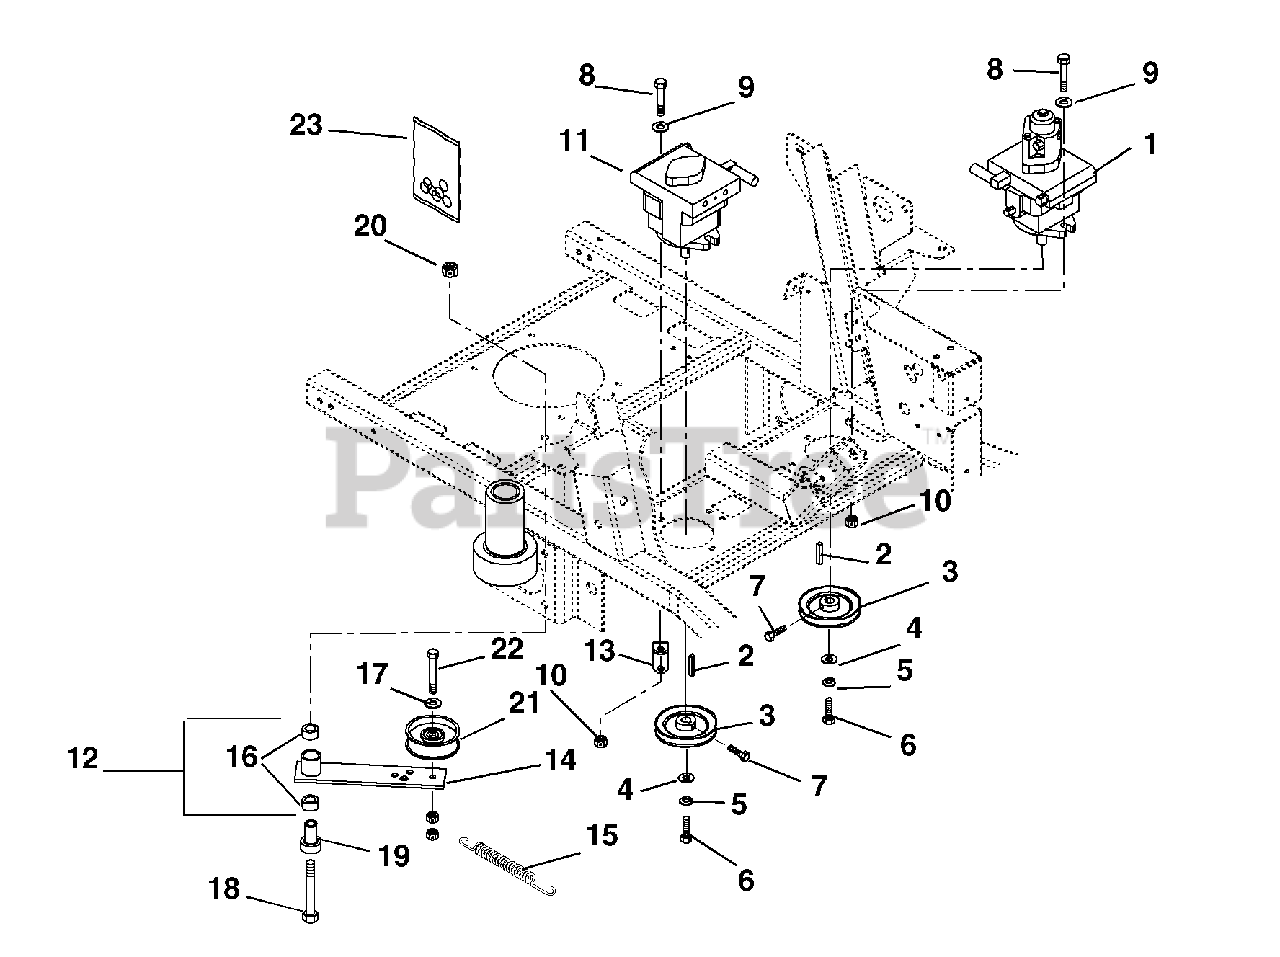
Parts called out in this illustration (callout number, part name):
1	Hydrostat BDP with Auxiliary
2	Key-Straight 5mm x 25mm x 5mm
3	Sheave 4.0 x .199
4	Washer-Flat-Steel .25 x 1.0 x .048
5	Washer-Locking .25 x .062
6	Bolt-Hex M6 x 1.0 x 12
7	Bolt-Hex .25-20 x .50 Grade 5
8	Bolt-Hex .38-16 x 1.25 Grade 5
9	Washer-Flat-Steel .390 x .75 x .125
10	Nut-Locking-Center .38-16
11	Variable-Displace Pump
12	Assembly,Idler Arm-Ground Drive
13	Anchor-Spring-Idler
14	Weldment, Idler Arm Ground Drive
15	Spring-Tension .120 x .845 x 6.500
16	Bearing, 1.00 x 1.12 x .75
17	Washer-Flat-Steel .39 x .75 x .125
18	Bolt-Hex .50-13 x 3.50 Grade 5
19	Bearing, Pedestal
20	Nut-Locking-Center .50-13
21	Assembly-Idler Pulley
22	Bolt-Hex .38-16 x 2.25 Grade 5
23	Kit-Pump Seal
